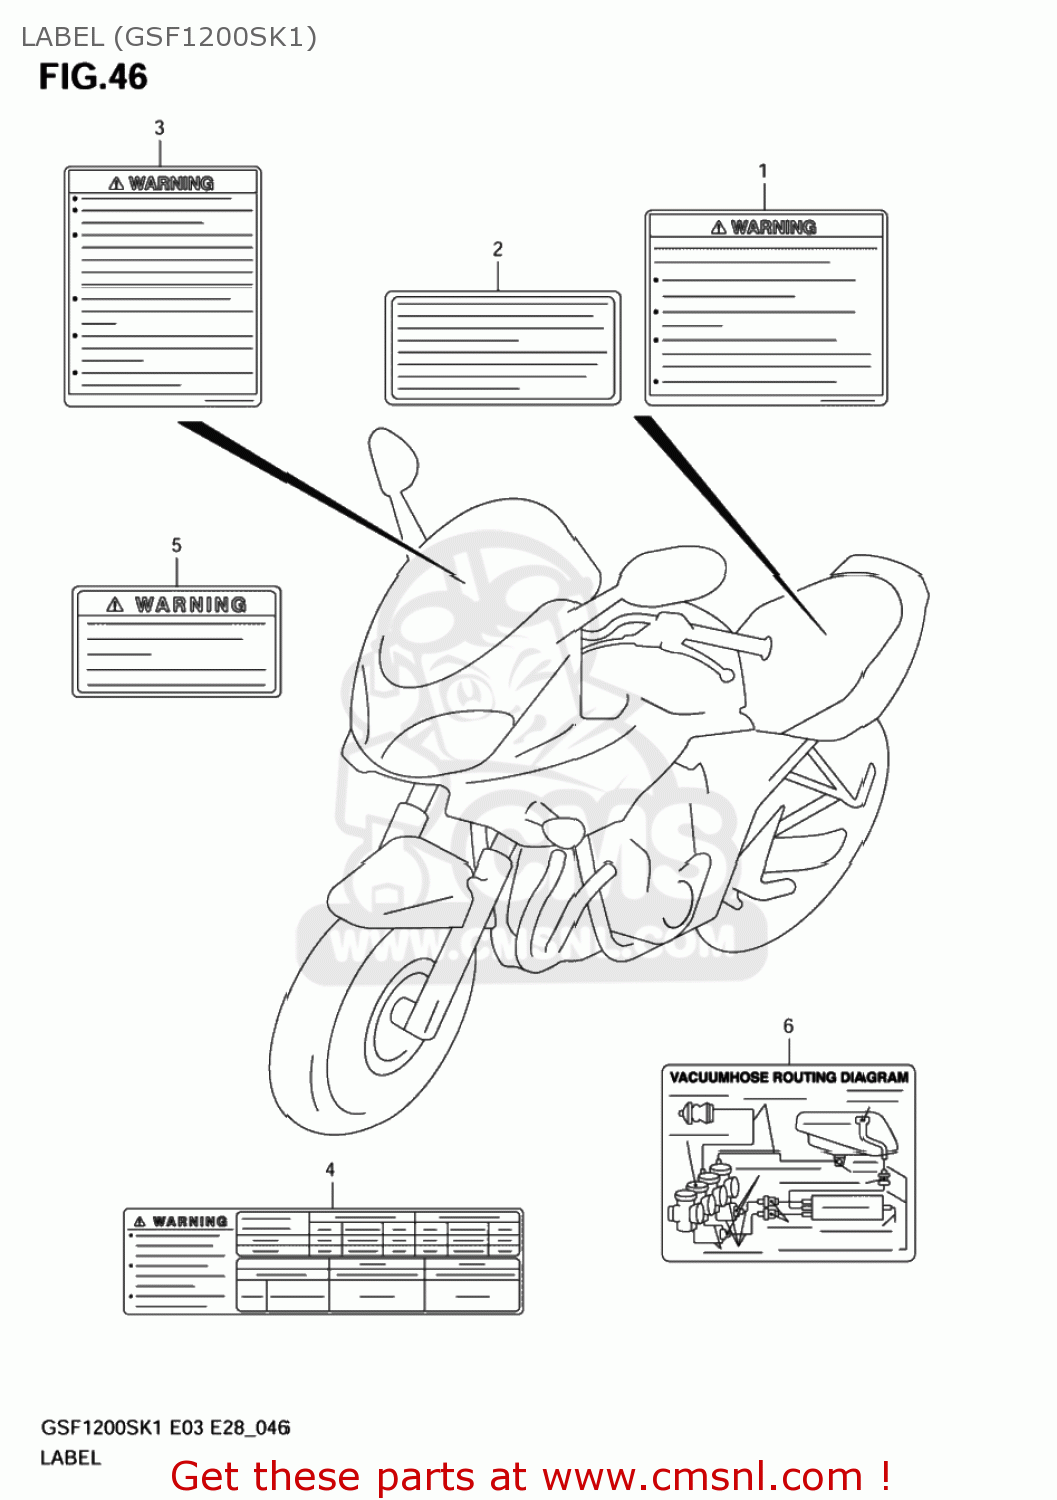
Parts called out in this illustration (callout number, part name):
1	LABEL,GENERAL WARNING
2	LABEL (MANUAL NOTICE)
3	LABEL,WARNING SCREEN
4	LABEL BANDEN
5	LABEL,WARNING STEERING
6	LABEL,VACUUM HOSE ROUTING
7	MANUAL,OWNER'S GSF1200Y
